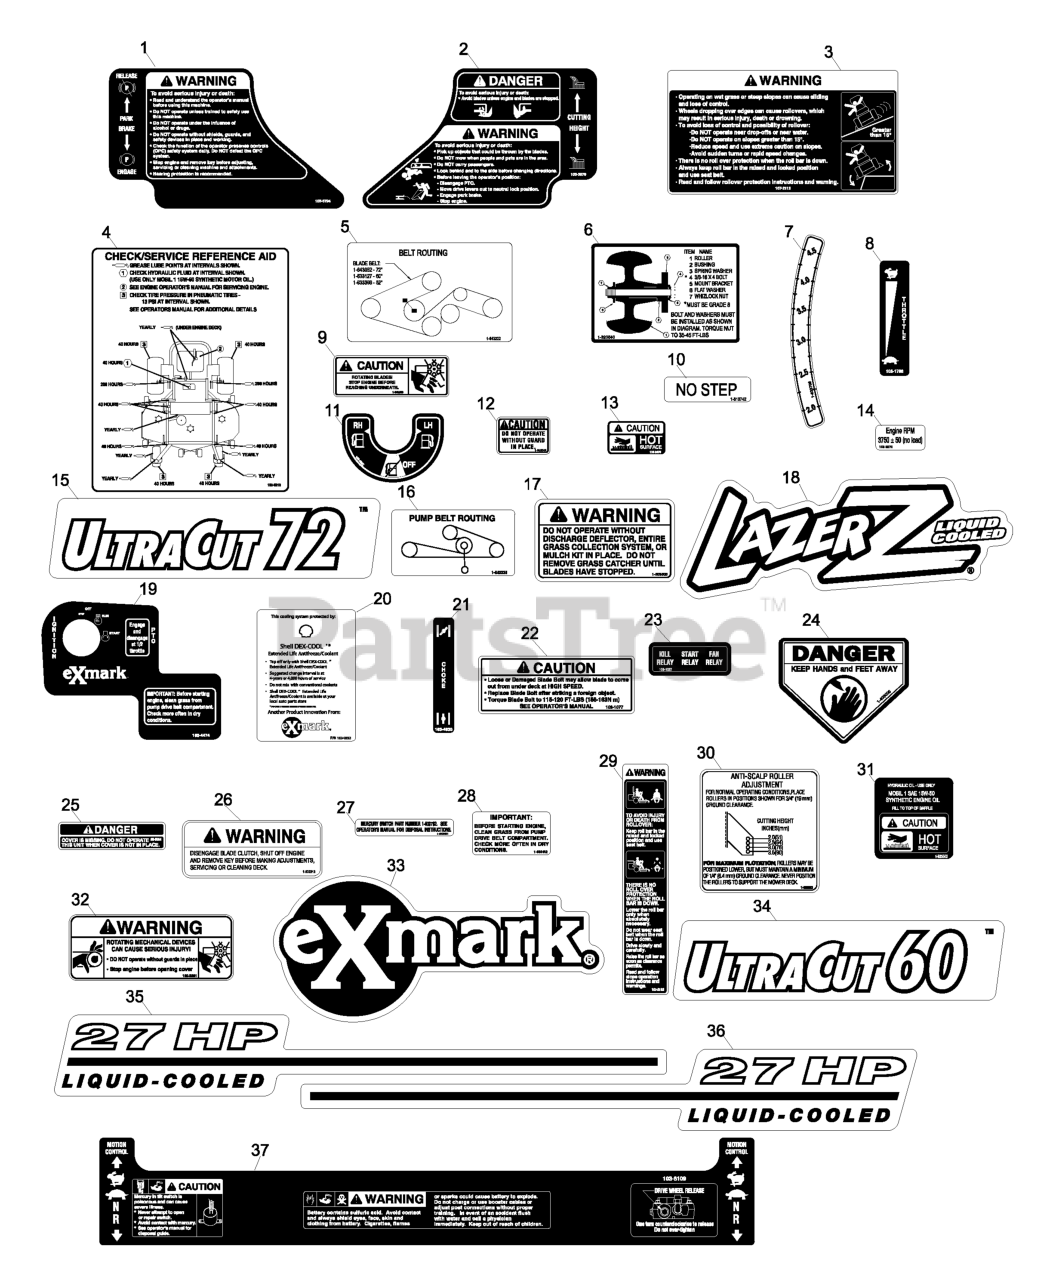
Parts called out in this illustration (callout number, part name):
1	DECAL,PARK BRAKE
2	DECAL,CUTTING HEIGHT
3	DECAL-WARNING
4	DECAL,CHECK SERVICE LZ
5	DECAL,BELT ROUTING
6	DECAL,ROLLER MOUNTING
7	DECAL-HEIGHT, DECK
8	DECAL,THROTTLE ONLY
9	DECAL-FAN, RADIATOR
10	DECAL,NO STEP
11	DECAL-VALVE, FUEL
12	DECAL-GUARD
13	DECAL-CAUTION
15	DECAL,ULTRACUT 72
16	DECAL-ROUTING, BELT
17	DECAL-WARNING, DISCHARGE
19	DECAL,IGNITION/PTO
20	DECAL,SHELL COOLANT
21	DECAL,CHOKE
22	DECAL,BOLT TORQUE
23	DECAL-RELAY
24	DECAL-DANGER
25	DECAL-COVER, MISSING
26	DECAL,WARNING
27	DECAL-SWITCH, MERCURY
28	DECAL-IMPORTANT
29	DECAL-WARNING, FOLDING RO
30	DECAL,ANTISCALP
32	DECAL-DEVICES, ROTATING
33	DECAL,EXMARK LOGO
34	DECAL,ULTRACUT 60
35	DECAL,HOOD 27LC LH
